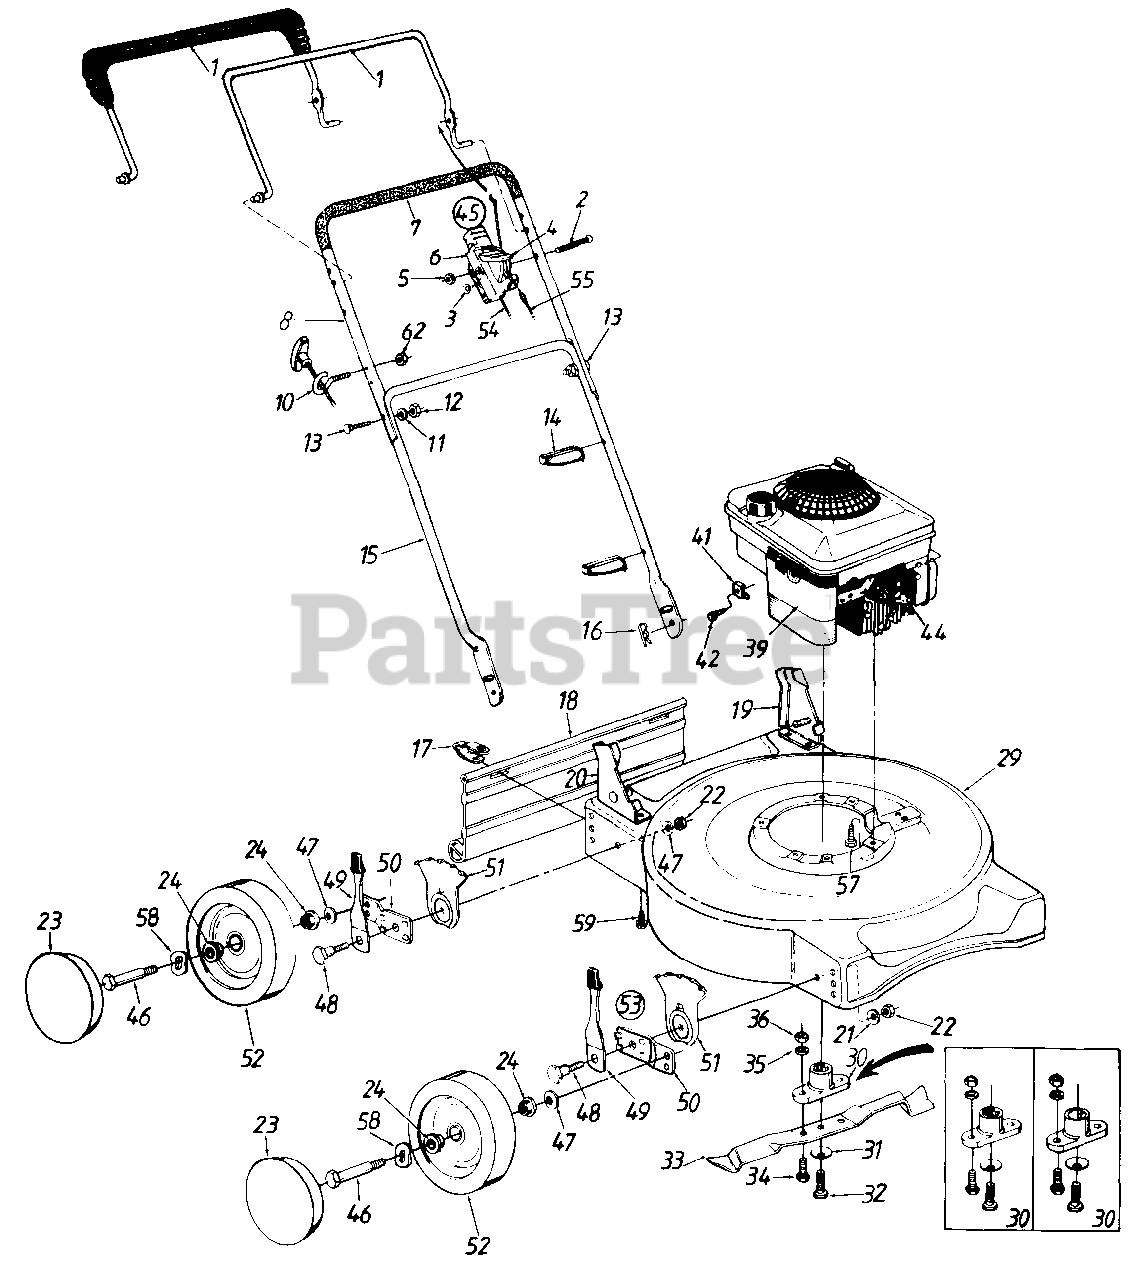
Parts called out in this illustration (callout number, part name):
1	Control Handle Ass'y.
2	Oval C-Sunk Scr.
3	Spr. Wash..66" I.D.
4	Throttle Lever
5	Hex L-Nut 1/4-20 Thd.
6	Throttle Body
7	Grip
11	L-Wash. 5/16" I.D.
12	Hex Nut 5/16-18 Thd.
13	Curved Carriage Bolt 5/16-18 x 1.38" Lg.
14	Cable Tie
15	Lower Handle
16	Hairpin Cotter
17	Hinge Clip
18	Rear Flap
19	Handle Bracket Ass'y. - L.H.
20	Handle Bracket Ass'y. - R.H.
21	Bell-Wash..39" I.D. x 1.38"
22	Hex Nut 3/8-16 Thd.
23	Hub Cap Gray (5-1/2 Dia.)
24	Ball Brg. 1/2" I.D.
29	20" Deck Ass'y.
30	Blade Adapter Kit
31	Bell-Wash..39" I.D.
32	Hex Bolt 3/8-24 x 1.5" Lg.
33	20" Mulching Blade
34	Hex Bolt 3/8-24 x 1" Lg.
35	L-Wash. 3/8" I.D.
36	Hex Nut 3/8-24 Thd.
39	Engine
41	Cable Clamp
42	Hex Self-Tap Scr. #10-32 x .62"
45	Throttle Box Comp.
46	Axle Bolt
47	Bell-Wash..400" I.D. x .88"
48	Shld. Bolt .50" Dia. x .357"
49	Spring Lever Ass'y. w/Knob
51	Height Adj. Plate
52	Wheel Ass'y. Comp. Diamond Tread (7")
53	Height Adj. Ass'y. Comp. - R.F. & L.R.
54	Throttle Cable - 51" (B&S)
55	Control Cable - 39" (B&S)
57	Hex L-Wash. Hd. Scr. 3/8-16 x 1.0" Lg.
58	Wave Washer .53" I.D.
59	Hex Wash. Hd. B-Tap Scr. 5/16-18 x .5" Lg.
62	Hex L-Nut 1/4-20 Thd.
